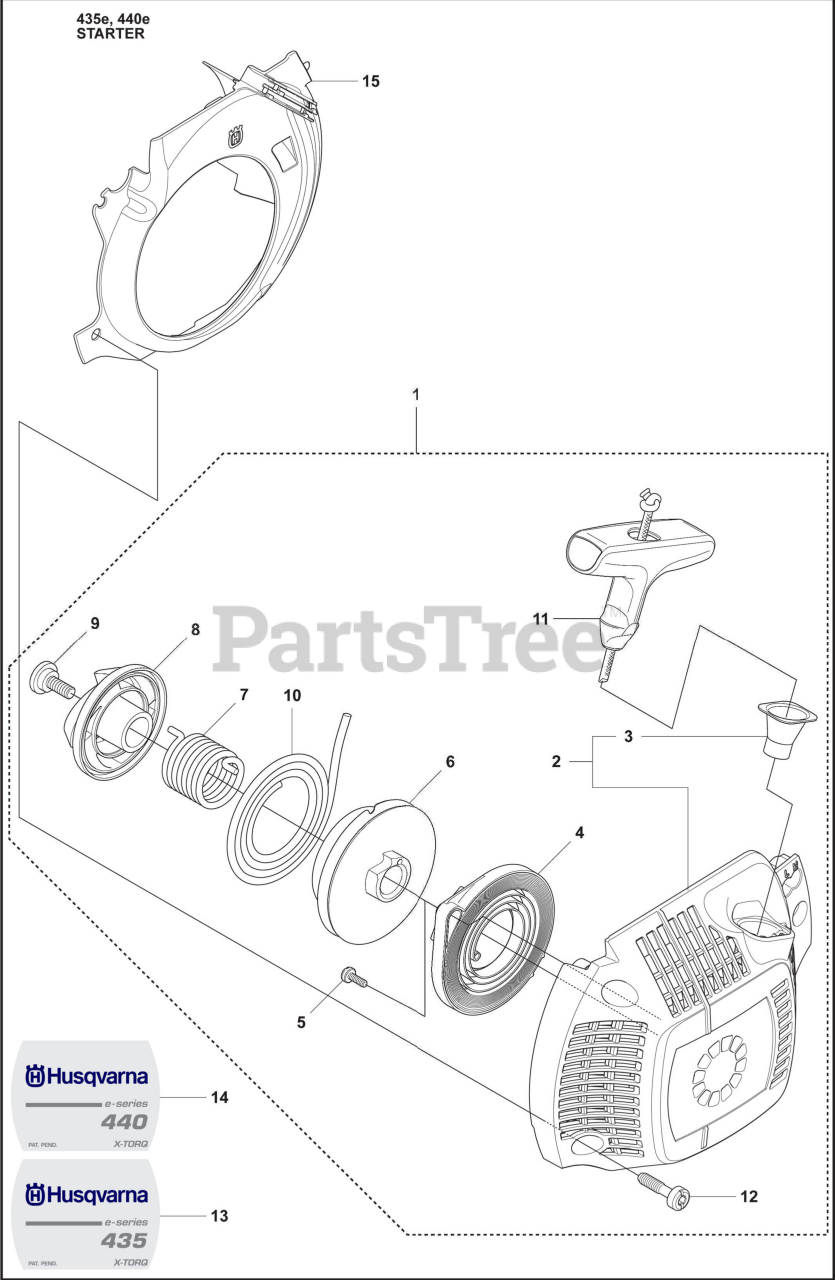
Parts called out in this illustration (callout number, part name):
1	Recoil Starter Assembly
2	Starter Housing
3	Sleeve
4	Cassette Assembly Spring
5	Screw
6	Starter Pulley
7	Spring
8	Starter Hub, EPS
9	Shoulder Screw
10	Starter Rope
11	Handle
12	Recoil Starter Screw
13	Label, 435 Starter
14	Label, 440 Starter
15	Air Cooling Conductor
